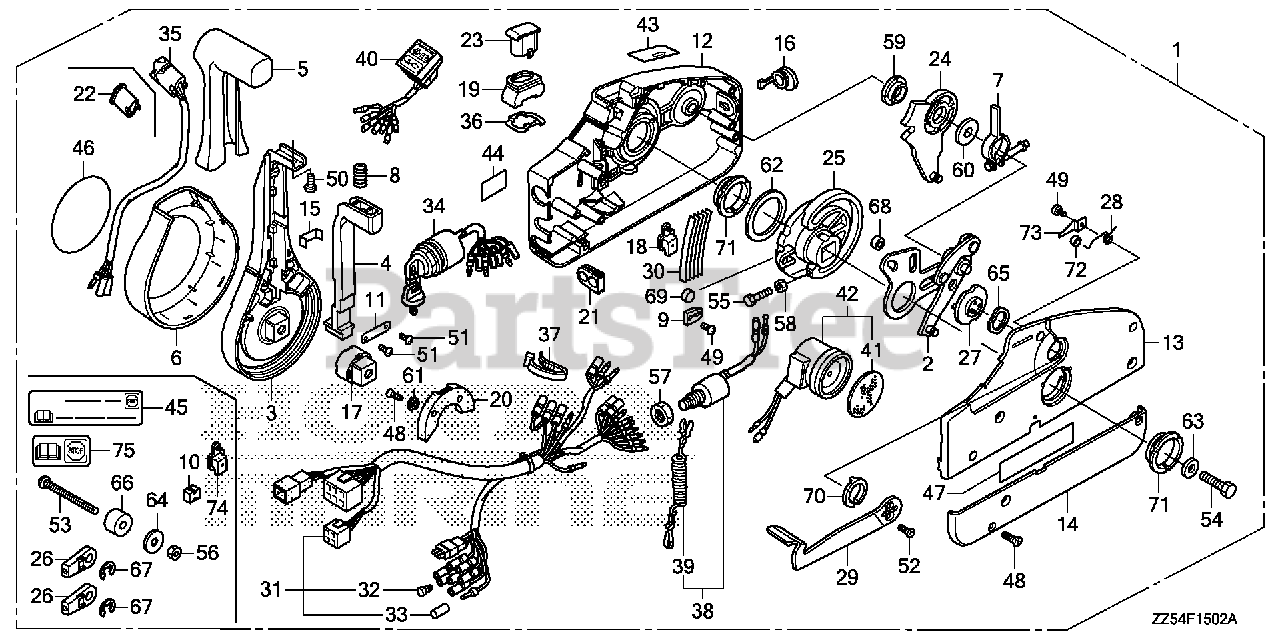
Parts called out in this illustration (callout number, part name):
1	BOX ASSY., REMOTE CONTROL (NHK MEC)
2	PLATE ASSY.
3	LEVER, HAND
4	ARM, NEUTRAL LOCK
5	GRIP
6	COVER, LEVER
7	ARM ASSY., BRAKE
8	SPRING (2)
9	CLIP, DETENT
10	SPACER (1) (LOOSE PARTS)
11	BRACKET
12	HOUSING, FR.
13	HOUSING, RR.
14	PANEL, BACK
16	CAP, RUBBER
17	ADJUSTER
19	SEAL, RUBBER
20	HOLDER, NEUTRAL LOCK
21	GROMMET, WIRE (14)
22	COVER, GRIP
23	CAP, TROLLING CONTROL SWITCH BLANK
24	GEAR ASSY., SHIFT
25	GEAR, DRIVE
26	TERMINAL, CABLE (LOOSE PARTS)
27	DRUM ASSY., FREE THROTTLE
28	SPRING (1)
29	LEVER, FREE THROTTLE
30	SPRING, DETENT
31	CABLE ASSY., REMOTE CONTROL (B)
32	PLUG, CONNECTOR (INNER)
33	PLUG, CONNECTOR (OUTER)
34	SWITCH ASSY., COMBINATION
36	PLATE, SWITCH
37	BAND, WIRE
38	SWITCH ASSY., EMERGENCY STOP
39	WIRE, EMERGENCY
40	LAMP ASSY., INDICATION
41	PLATE, TURN SIGNAL BUZZER
42	BUZZER, WARNING
43	MARK, FAST IDLE
44	MARK, EMERGENCY STOP (US)
45	MARK, EMERGENCY STOP (US) (LOOSE PARTS)
46	MARK, EMBLEM
47	LABEL, SIGP
48	SCREW (5X18)
49	SCREW (4X6)
50	SCREW (5X10)
51	SCREW (4X10)
52	SCREW (5X12)
53	SCREW (6X90) (LOOSE PARTS)
54	BOLT (8X50)
55	BOLT (5X25)
56	NUT (6MM) (LOOSE PARTS)
57	NUT, HEX. (16MM)
58	NUT (5MM)
59	BEARING (1)
60	WASHER (3)
61	WASHER (4)
62	WASHER (5)
63	WASHER (8MM)
64	WASHER (7) (LOOSE PARTS)
65	WASHER, WAVE
66	SPACER (2) (LOOSE PARTS)
67	E-RING (6MM) (LOOSE PARTS)
68	ROLLER, DRIVE GEAR CAM
69	ROLLER
70	BEARING (2)
71	BEARING (3)
72	ROLLER, FREE THROTTLE
73	CLIP, ROLLER
